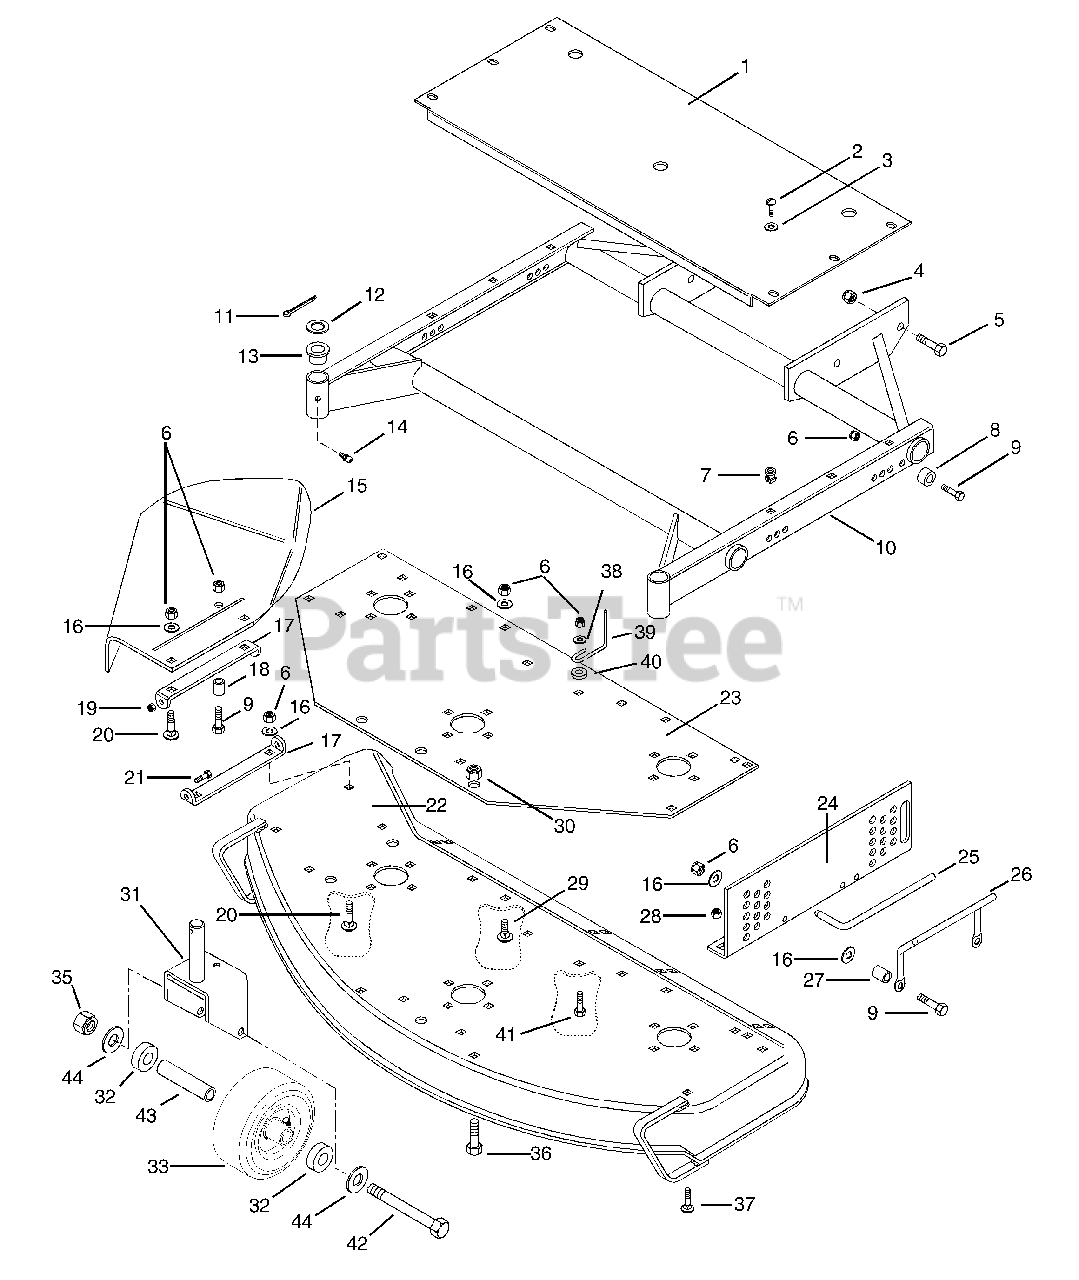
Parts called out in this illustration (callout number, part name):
1	Guard, 50" Mower Belt
2	Screw-Tapping .25-20 x .50
3	Washer-Flat-Steel .281 x .620 x .065
4	Nut-Locking-Nylon .625-11 Grade 2
5	Bolt-Hex .625-11 x 1.50
6	Nut-Locking-Nylon .375-16 Grade 2
7	Grommet, Plastic
8	Bushing .391 x .626 x .670
9	Bolt-Hex .38-16 x 1.50 Grade 5
10	Mower Frame, 50", Pro 150
11	Pin-Cotter .188 x 1.50
12	Washer-Hardened Thrust 1.002 x 1.552 x .030
13	Bushing-Flange 1.020 x 1.385 x .75 x 1.75
14	Fitting-Lube .25-28 x .256
15	Shield, Safety External 50" Mower
16	Washer-Flat-Steel .406 x .812 x .065
17	Bracket, Chute
18	Bushing-Sleeve .407 x .625 x .750
19	Nut-Locking-Nylon .250-20 Grade 2
20	Bolt-Round Head Square Neck .38-16 x 1.0
21	Bolt-Hex .25-20 x .875
22	Weldment, 50" Mower
23	Plate, Support
24	Bracket, Mower Side Support Left Hand
24	Bracket, Mower Side Support Right Hand
25	Pin, Mower Locking
26	Handle
27	Bushing
28	Nut-Locking-Nylon .312-18 Grade 2
29	Bolt-Round Head Square Neck .375-16 x .75 Grade 1
30	Nut-Locking-Nylon .50-13 Grade 5
31	Weldment, Caster Fork
32	Spacer .755 x 1.25 x .37
33	Wheel 9 x 3.50
34	Bearing, Ball
35	Nut-Locking-Ctr .50-13
36	Bolt-Hex .50-13 x 1.25 Grade 5
37	Bolt, Round Head Square Neck .31-18 x 1.0
38	Washer-Flat-Steel .406 x 1.000 x .188
39	Belt Brake Finger 2-Deck Clutch
40	Bushing Flange .383 x .50 x .165
41	Bolt-Hex .38-16 x 1.25 Grade 5
42	Bolt-Hex .50-13 x 5.50 Grade 5
44	Washer .754 x 1.00 x .032
